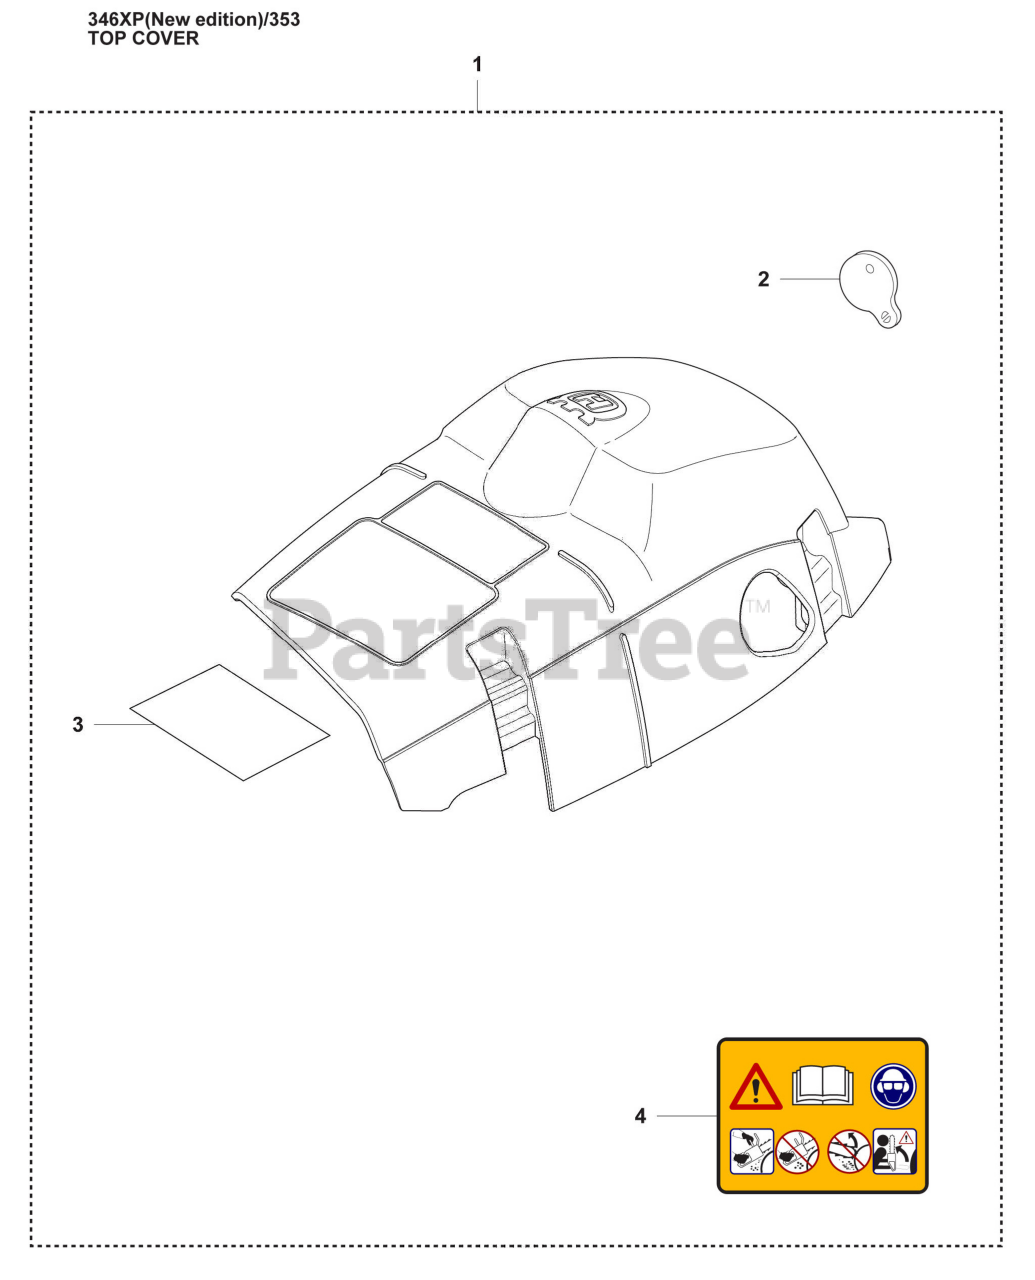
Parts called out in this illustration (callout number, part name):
1	Cylinder Cover Assembly
2	Plug
3	Insulating Foil/Cylinder Cover
